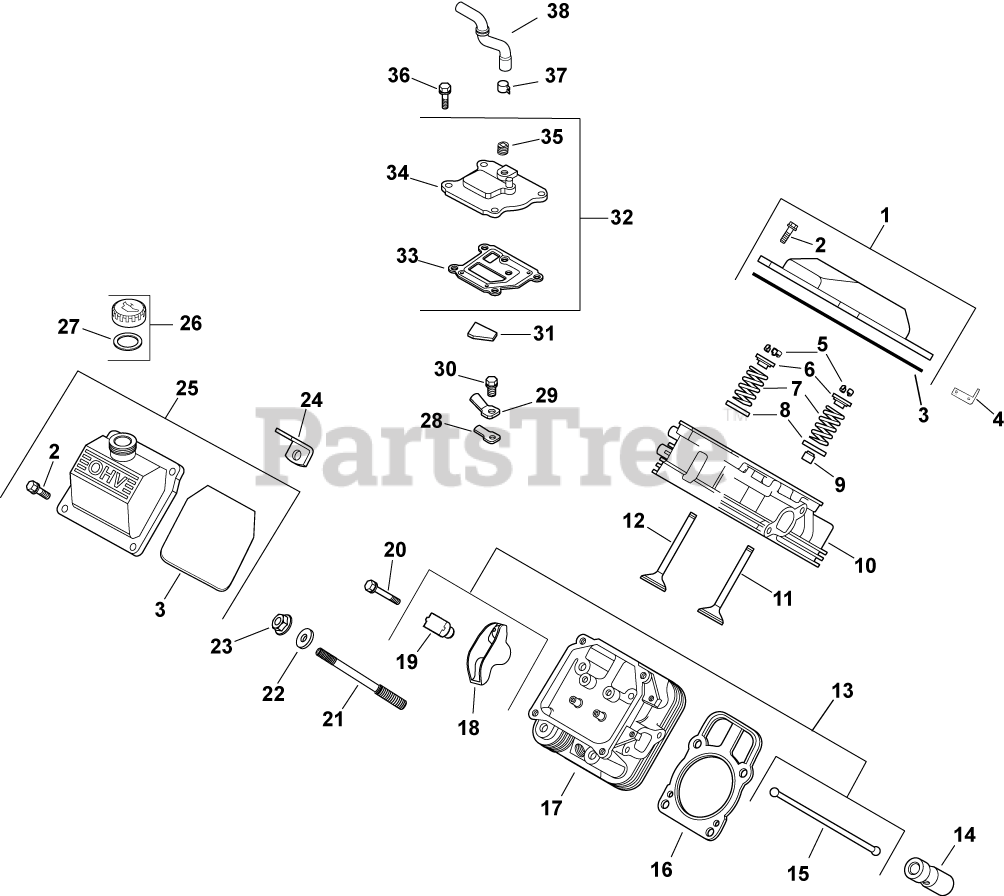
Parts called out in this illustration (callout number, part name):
1	KIT, VALVE COVER-PLAIN
2	SCREW, FLG M6X1.0X30
3	O-RING (YELLOW), VALVE COVER
4	STRAP, LIFTING-USE 25 445 03-S
5	KIT, RETAINER
6	RETAINER, VALVE SPRING - USE 25 173 28-S
7	SPRING, VALVE
8	RETAINER, SPRING
9	SEAL, VALVE STEM - (#2503214S)
10	KIT, CYLINDER HEAD #1 - (#24318143S)
11	VALVE, INTAKE (STD)
12	VALVE, EXHAUST (STD) - USE 32 016 01-S
13	KIT, VALVE TRAIN
14	LIFTER, HYDRAULIC VALVE-USE 25 351 10-S
15	ROD, PUSH
16	CYL HEAD GASKET KIT-USE 24 841 04-S
17	KIT, CYLINDER HEAD #2 USE 24 318 149-S
18	ARM, ROCKER
19	PIVOT, ROCKER ARM
20	SCREW, FLG M6X1.0X34
21	STUD, M8X1.25
22	WASHER, FLAT 8.6 MM
23	NUT, FLG M8X1.25
24	STRAP, LIFTING
25	KIT, VALVE COVER-OIL FILL
26	KIT, OIL FILL CAP (YELLOW)
27	O-RING, DIPSTICK
28	REED, BREATHER
29	RETAINER, REED
30	SCREW, FLG THD FRM M5X.8X10
31	FILTER, BREATHER
32	KIT, BREATHER ASSEMBLY
33	GASKET, BREATHER-USE 24 041 67-S
34	COVER, BREATHER -USE 24 033 01-S
35	PLUG, CTSK PIPE 1/8"
36	SCREW,FLG THD FRM M6X1.0X20-(#25086396S)
37	CLAMP, HOSE (KM)-USE 25 237 31-S
38	HOSE, BREATHER
2401602-S	VALVE, EXHAUST (.25)
2401702-S	VALVE, INTAKE (.25)
